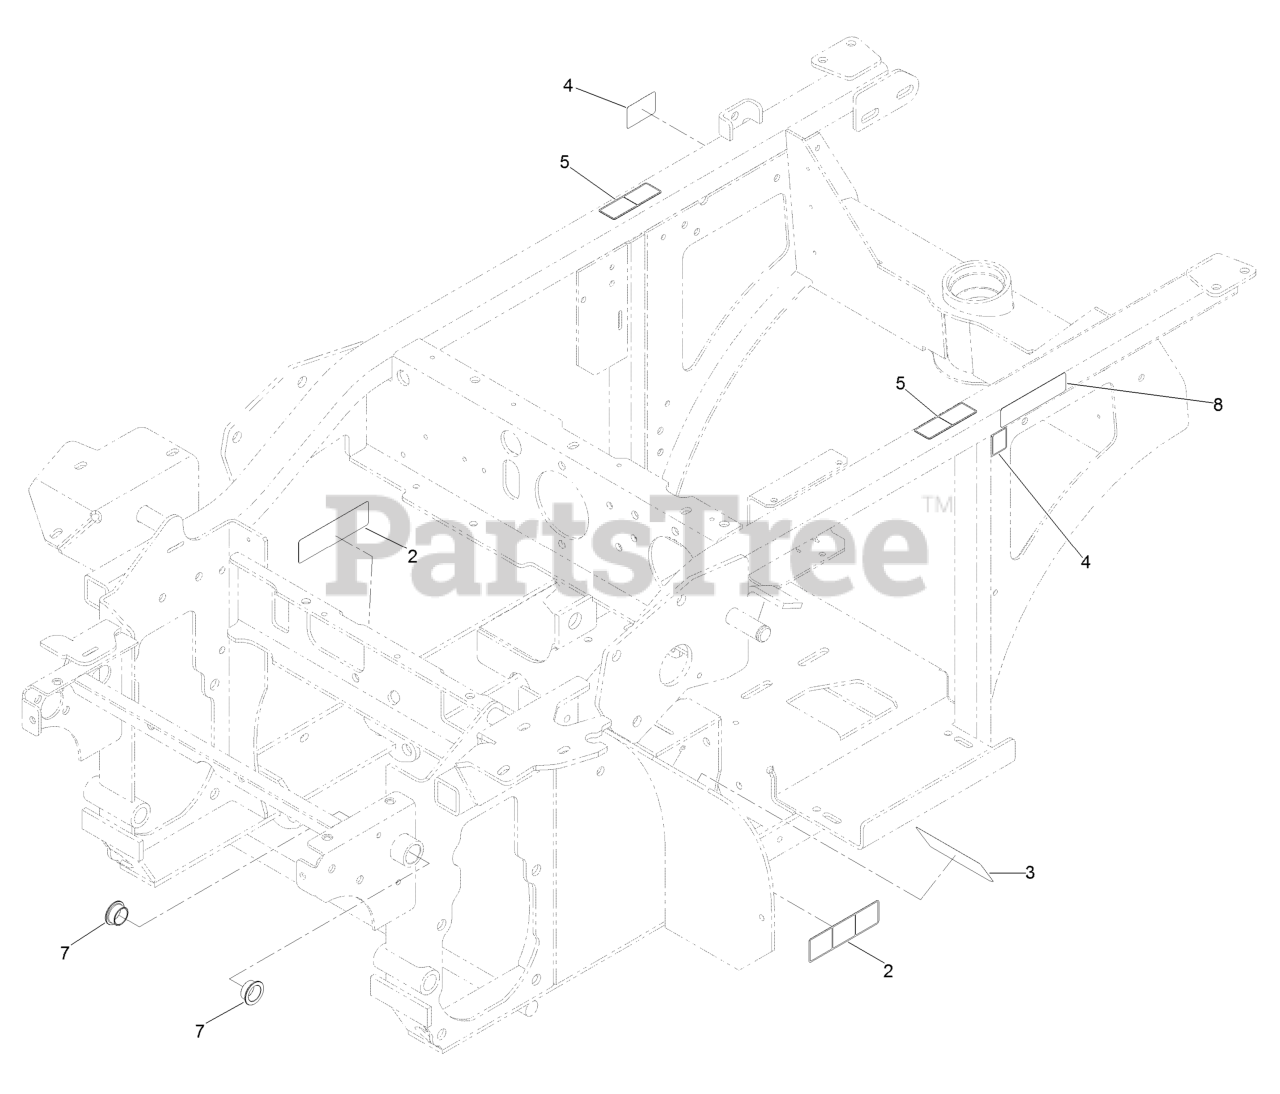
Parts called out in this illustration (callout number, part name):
2	Decal-Missing, Cover
3	Decal-Adjustment, Clutch
4	Decal-Warning
5	Decal-Warning, Pinch Point
7	Bushing-Bronze
8	Decal-Arrester, Spark
